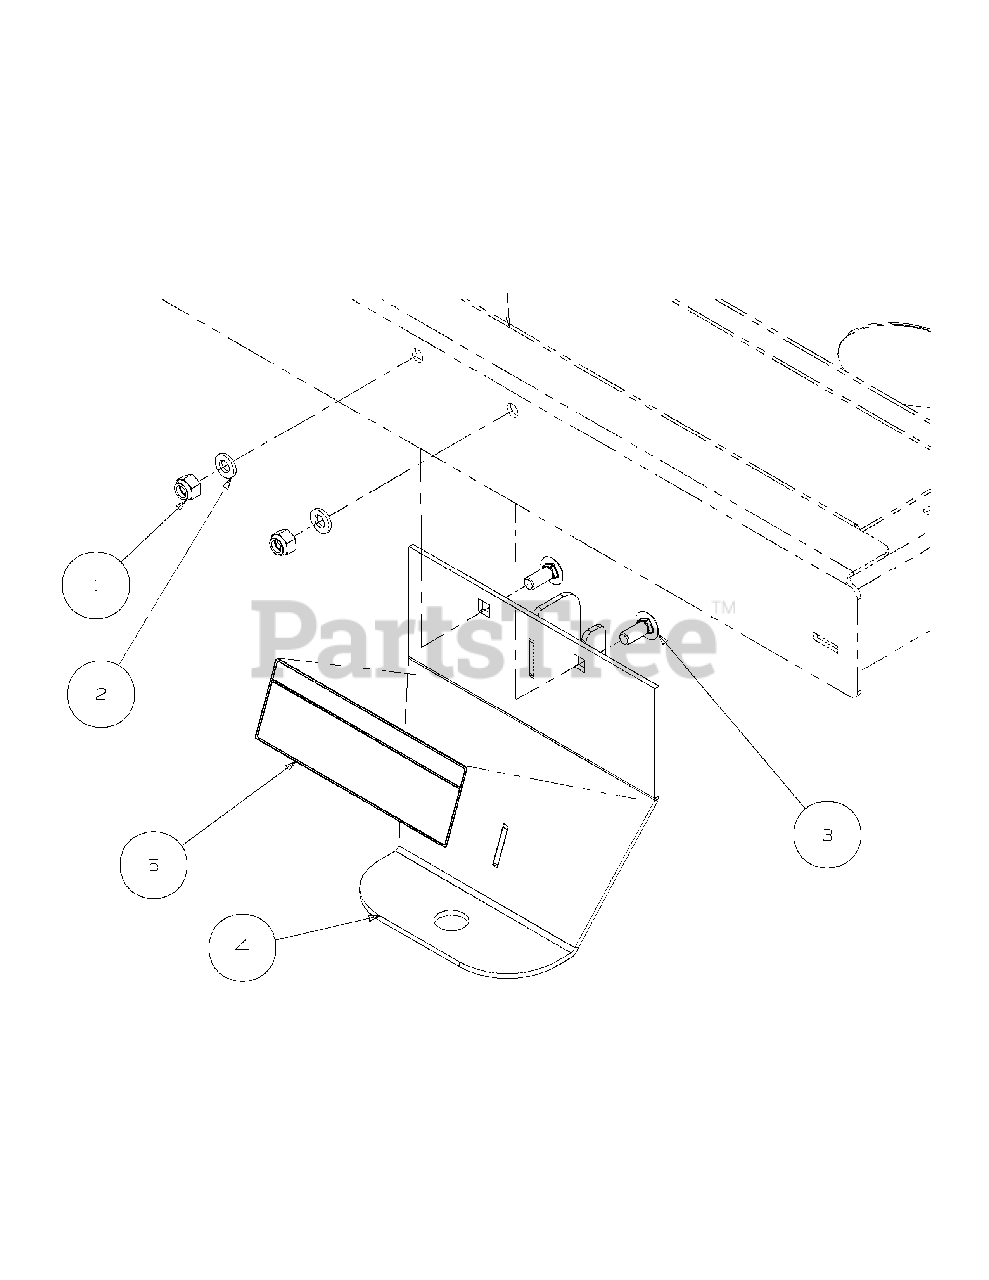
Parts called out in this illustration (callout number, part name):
1	Nylock Nut, 5/16-18
2	Flat Washer, .320 ID x .591 OD x .078
3	Carriage Bolt, 5/16-18 x .75
4	Hitch
5	Decal, Hitch Warning
